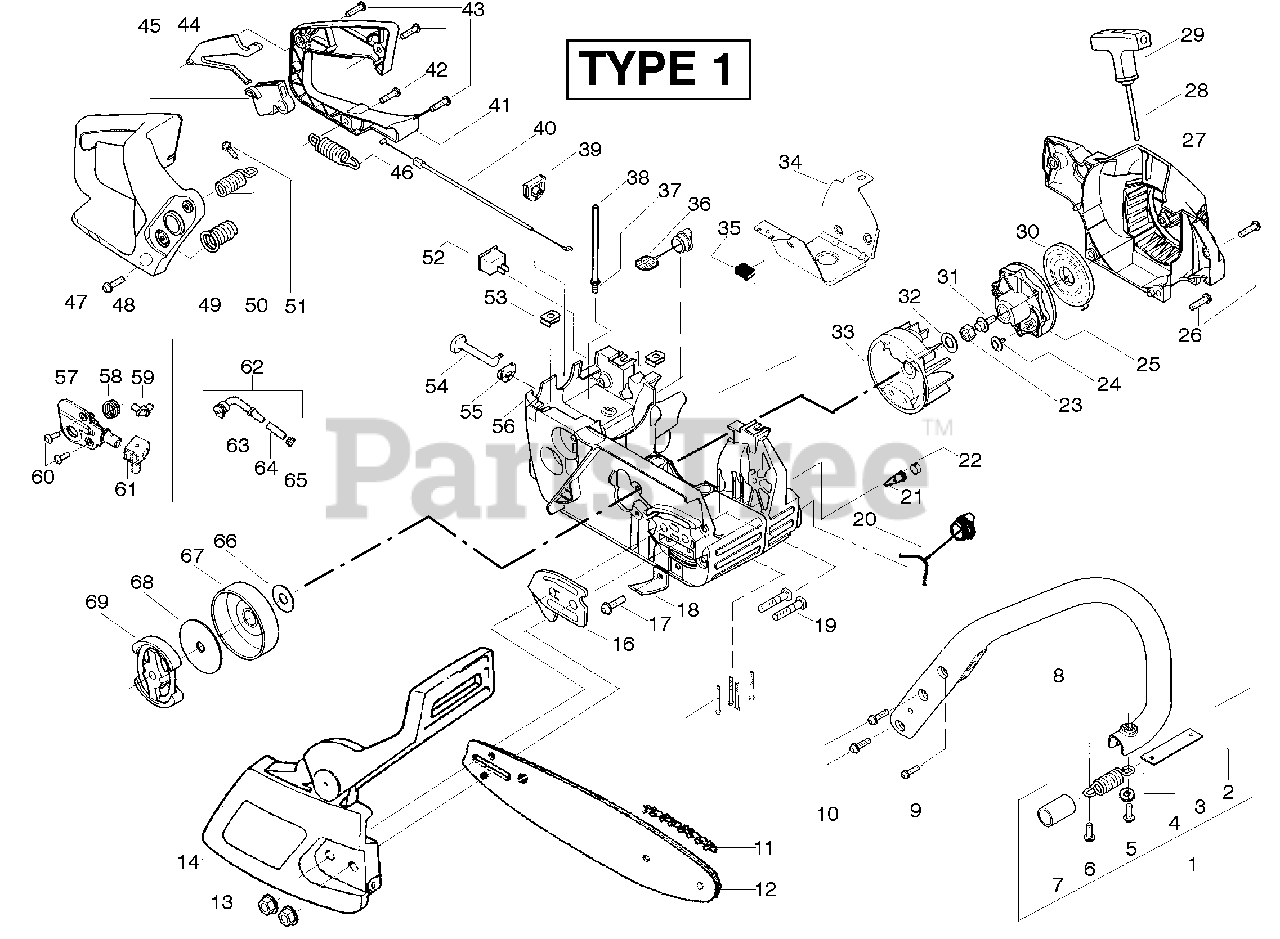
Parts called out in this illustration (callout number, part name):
1	Assy.- Isolator
2	Strap-Limiter
3	Spring-Isolator
7	Sleeve-AV Spring
8	Handle-Front
11	Chain-16"
12	Bar-16" Quick Adjust
13	Nut-Bar Mounting
14	Kit-Chain Brake
16	Plate-Bar Mounting
18	Chain Catcher
19	Bolt-Bar
20	Assy-Oil Cap
21	Check Valve
22	Plug-Bronze Vent
23	Nut-Flywheel
25	Pulley-Starter
27	Housing-Fan
28	Kit - Rope
29	Handle-Starter
30	Spring-Recoil
32	Washer-Flywheel
33	Assy-Flywheel
34	Shield - Heat
35	Clip - "U"
36	Assy-Fuel Cap
37	Fitting-fuel line
38	Kit-Fuel line (large)
39	Grommet-Cable
40	Cable-Throttle
41	Cover-Rear Handle
44	Throttle Lockout
45	Trigger-Throttle
46	Spring-Isolator
47	Handle - Rear
49	Assy. -Lower Isolator
50	Kit- Upper Isolator
52	Kit-Switch
53	Nut- "U"-Type
54	Knob-Choke
55	Grommet-Knob
56	Assy-Chassis
57	Kit - Oil Pump
58	Gear-Worm Spring
59	Elbow-Oil Pickup
61	Seal Block
62	Assy-Oil Pickup
63	Pick-up Oiler
64	Filter-Oil
65	Plug-Oil Filter
66	Washer-Thrust
67	Assy.-Clutch Drum w/bearing
68	Washer-Clutch
69	Assy. Clutch
